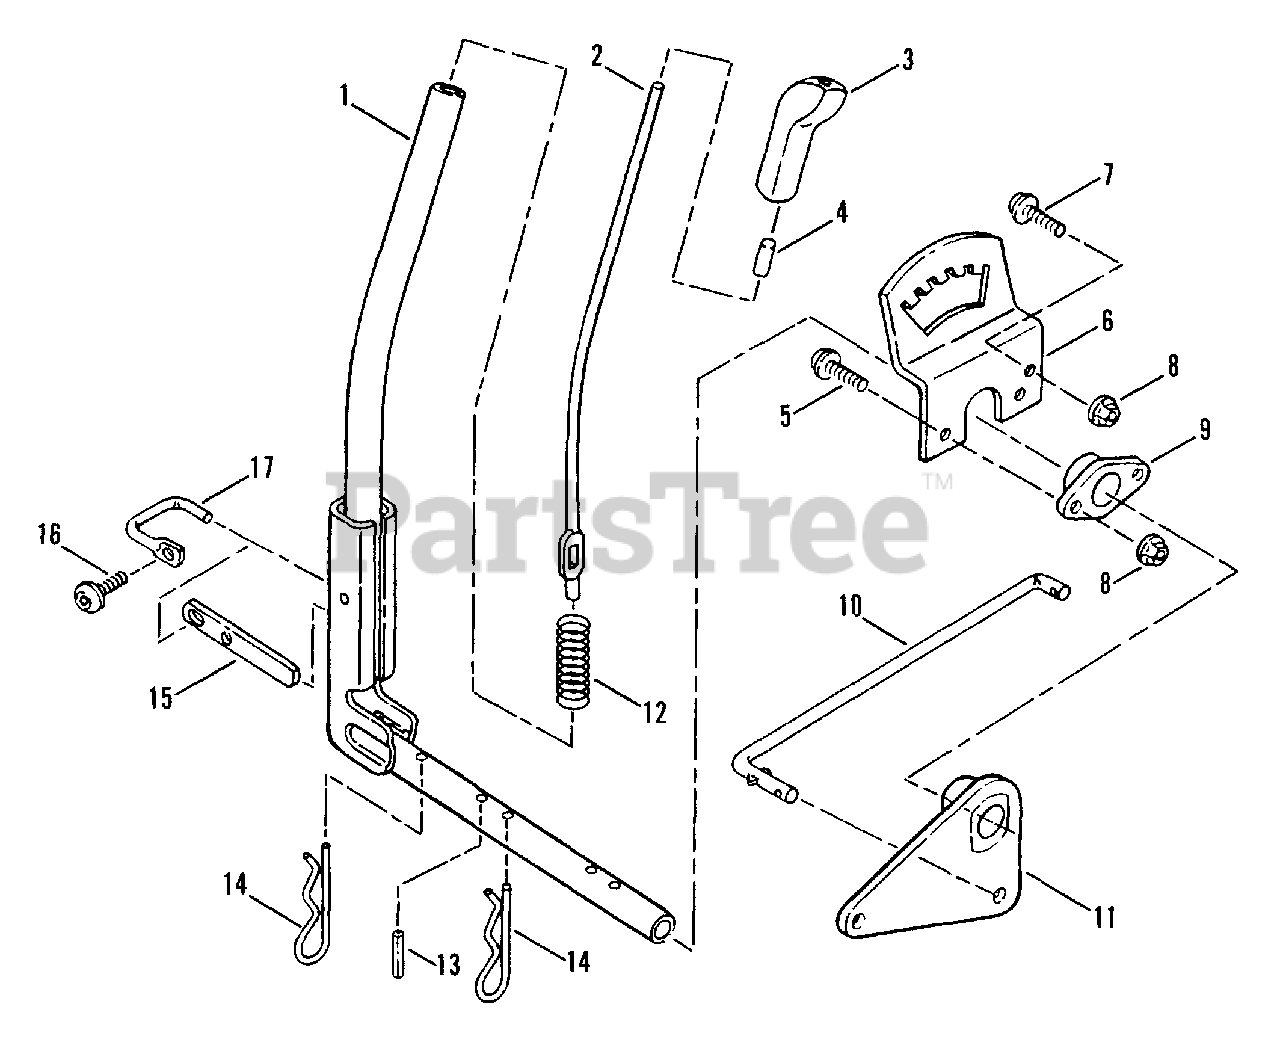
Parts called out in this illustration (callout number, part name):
1	STRUCTURE, Lift Lever
2	ROD, Lift Lever
3	KNOB, Lift Lever
4	CAP, Lever Rod
5	SCREW, 5/16-18 x 7/8" Truss Head (Torx)
6	QUADRANT, Lift Lever
7	SCREW, 5/16-18 x 5/8" Truss Head (Torx)
8	NUT, 5/16-18 Hex Flange Lock
9	PIVOT, Lift Lever
10	ROD, Lift Link
11	BELLCRANK, Lift Structure
12	SPRING, Lift Lever Rod
13	PIN, 1/4 x 1 1/8" Dowel
14	PIN, 5/32 x 2 5/8" Hair
15	DETENT, Latch
16	SCREW, 1/4-20 x 5/8" Truss Head (Torx)
17	LATCH, Pivot
